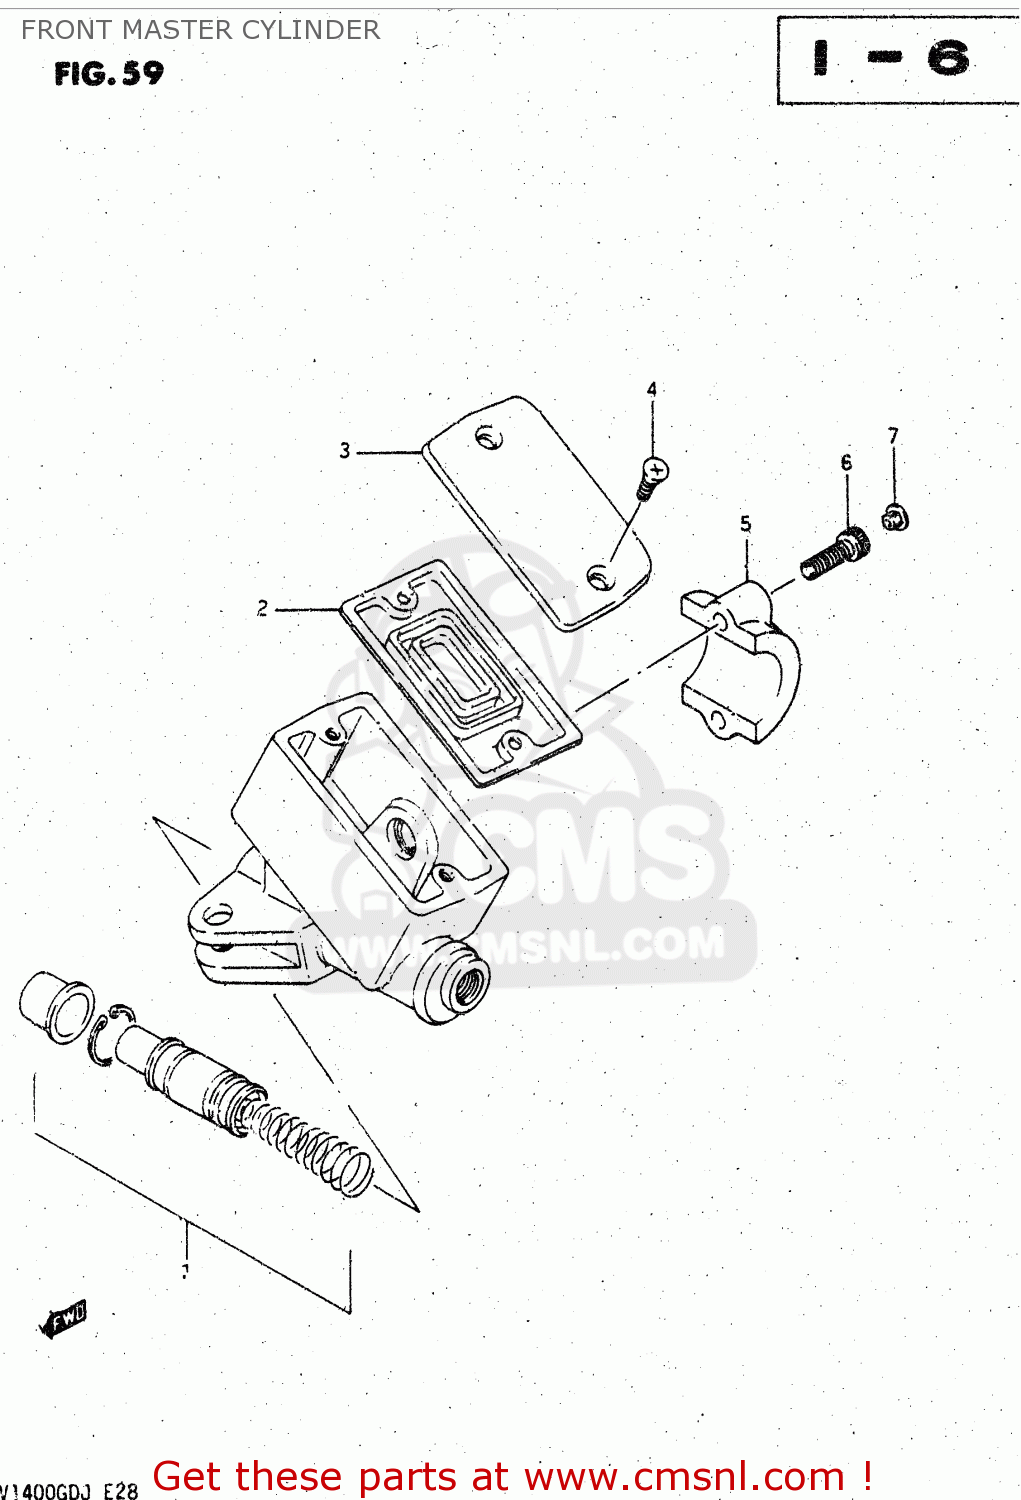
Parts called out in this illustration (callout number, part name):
1	PISTON & CUP SET
2	3
3	CAP
4	SCREW
5	HOLDER,MASTER CYLINDER
6	BOLT
7	CAP(OD:10)
